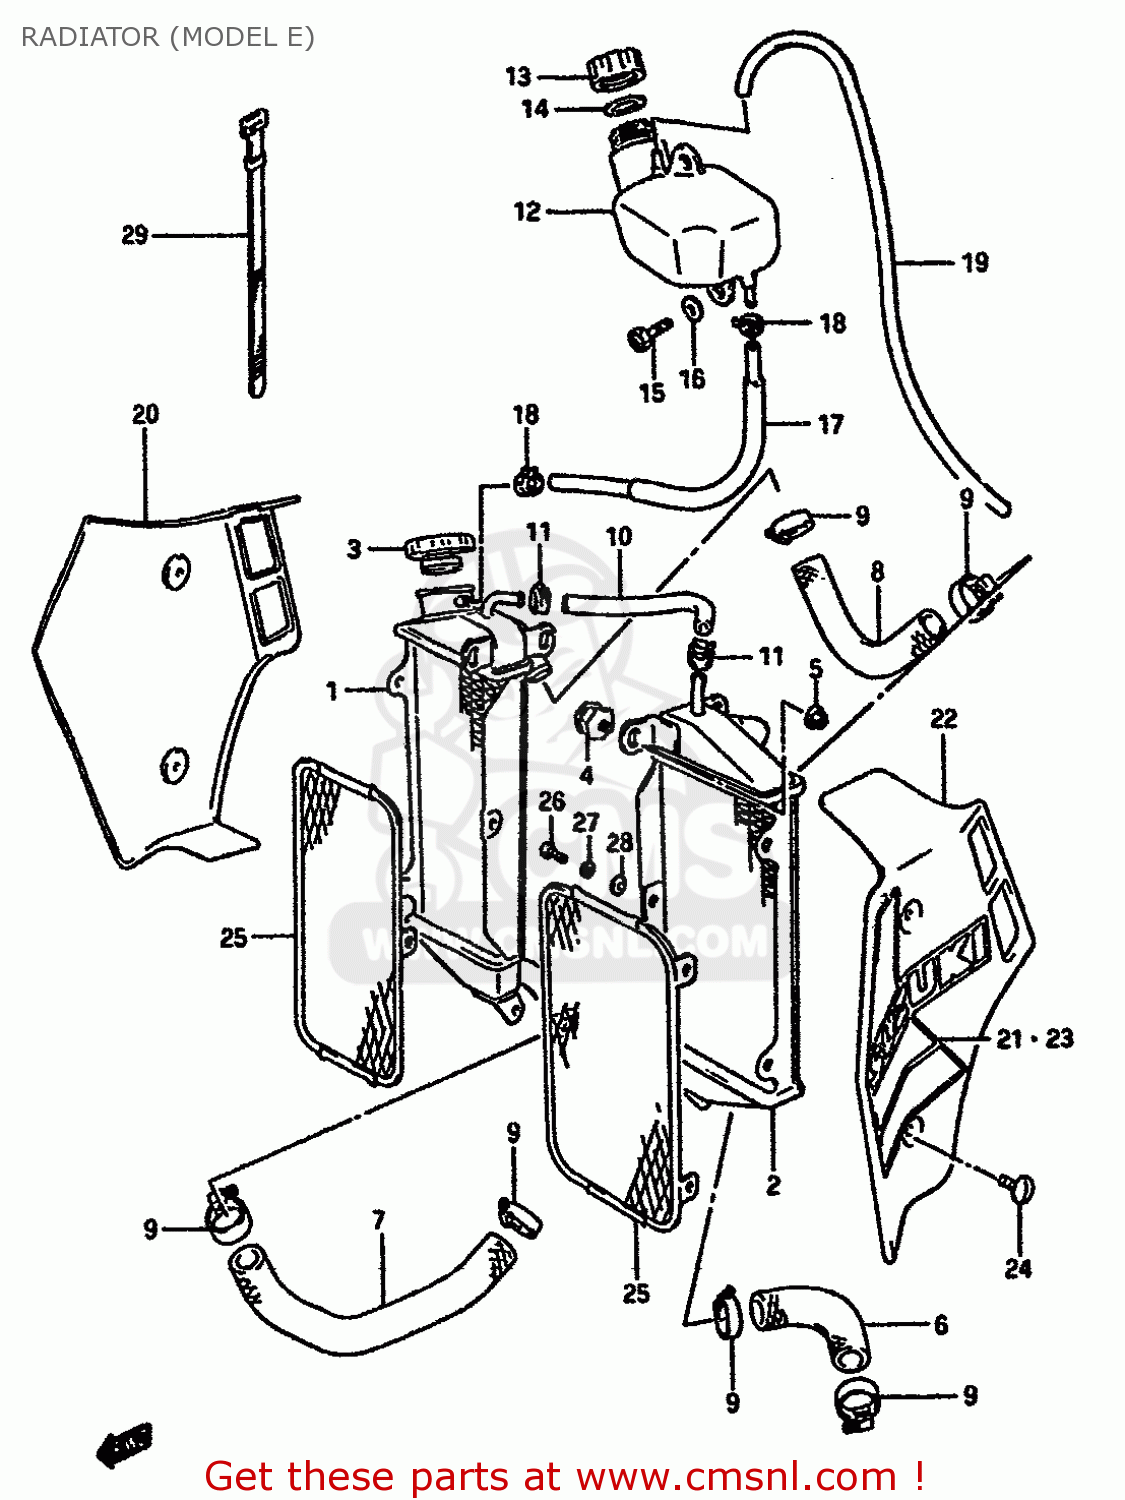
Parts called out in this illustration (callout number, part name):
1	RADIATOR,WATER,RH
2	RADIATOR,WATER,LH
3	CAP
4	BOLT,RADIATOR CUSHION
5	NUT 6MM
6	HOSE,RADIATOR,INLET
7	HOSE,RADIATOR,OUTLET
8	HOSE,RADIATOR,JOINT
9	CLAMP
10	HOSE,RADIATOR BY-PASS
11	CLIP
12	TANK ASSY,RESERVER
13	CAP,RESERVOIR TANK
14	GASKET,RESERVOIR TANK CAP (NAS)
15	SCREW
16	WASHER
17	HOSE,RESERVER TANK INLET
18	CLIP
19	HOSE
20	COVER,RADIATOR RH (RED)
21	TAPE SET,RADIATOR COVER RH
22	COVER,RADIATOR LH (RED)
23	TAPE SET,RADIATOR COVER LH
24	SCREW(6X14)
25	BUMPER,RADIATOR
26	SCREW
27	WASHER,LOCK
28	WASHER
29	CLAMP(L:220)
